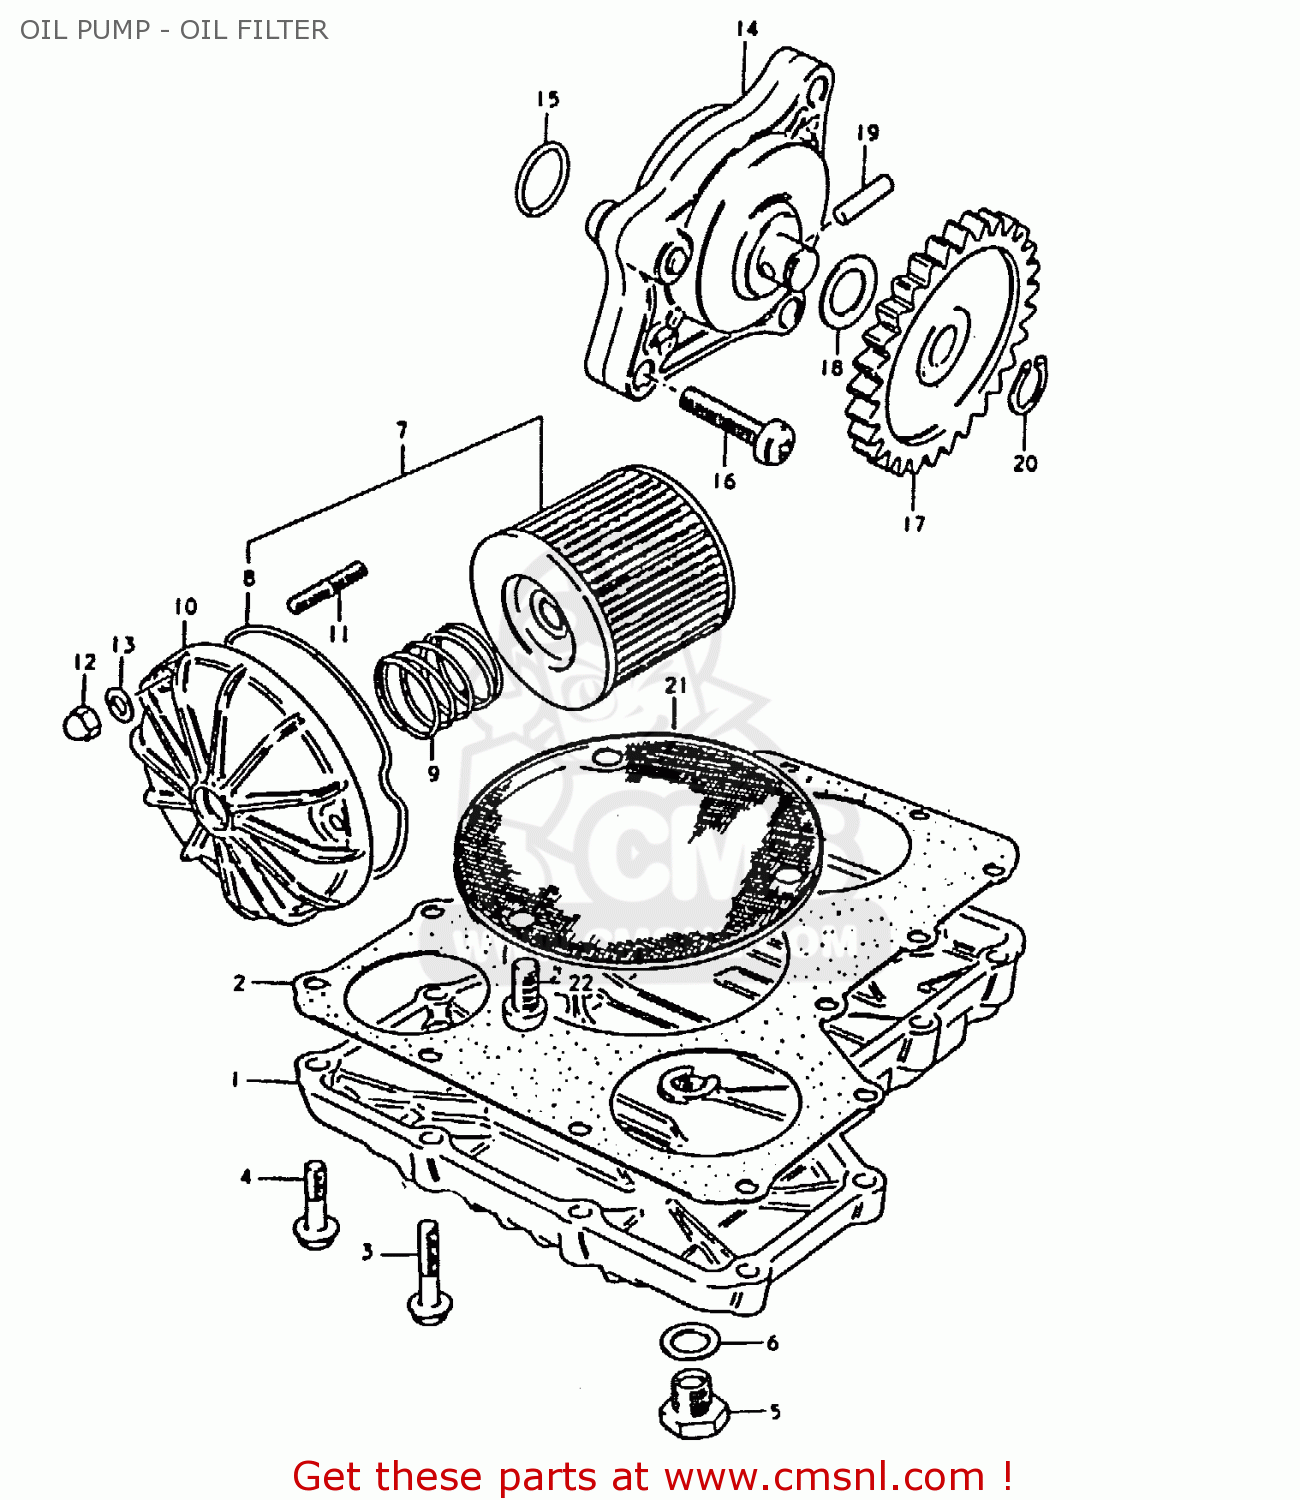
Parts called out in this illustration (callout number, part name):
1	PAN,OIL
2	GASKET,OIL PAN (MCA)
3	BOLT
4	BOLT
5	PLUG
6	GASKET(14X19.2X2) (NAS)
7	ENGINE OIL FILTER SET
8	O RING,OIL FILTER CHAMBER CAP
9	SPRING
10	CAP,OIL FILTER
11	STUD 6X20
12	NUT
13	WASHER
14	PUMP ASSEMBLY,OIL
15	O RING(D:1.9,ID:13)
16	SCREW
17	GEAR,OIL PUMP DRIVEN
18	SHIM
19	PIN(4X15.8)
20	CIRCLIP
21	STRAINER,ENGINE OIL
22	SCREW 6X12
